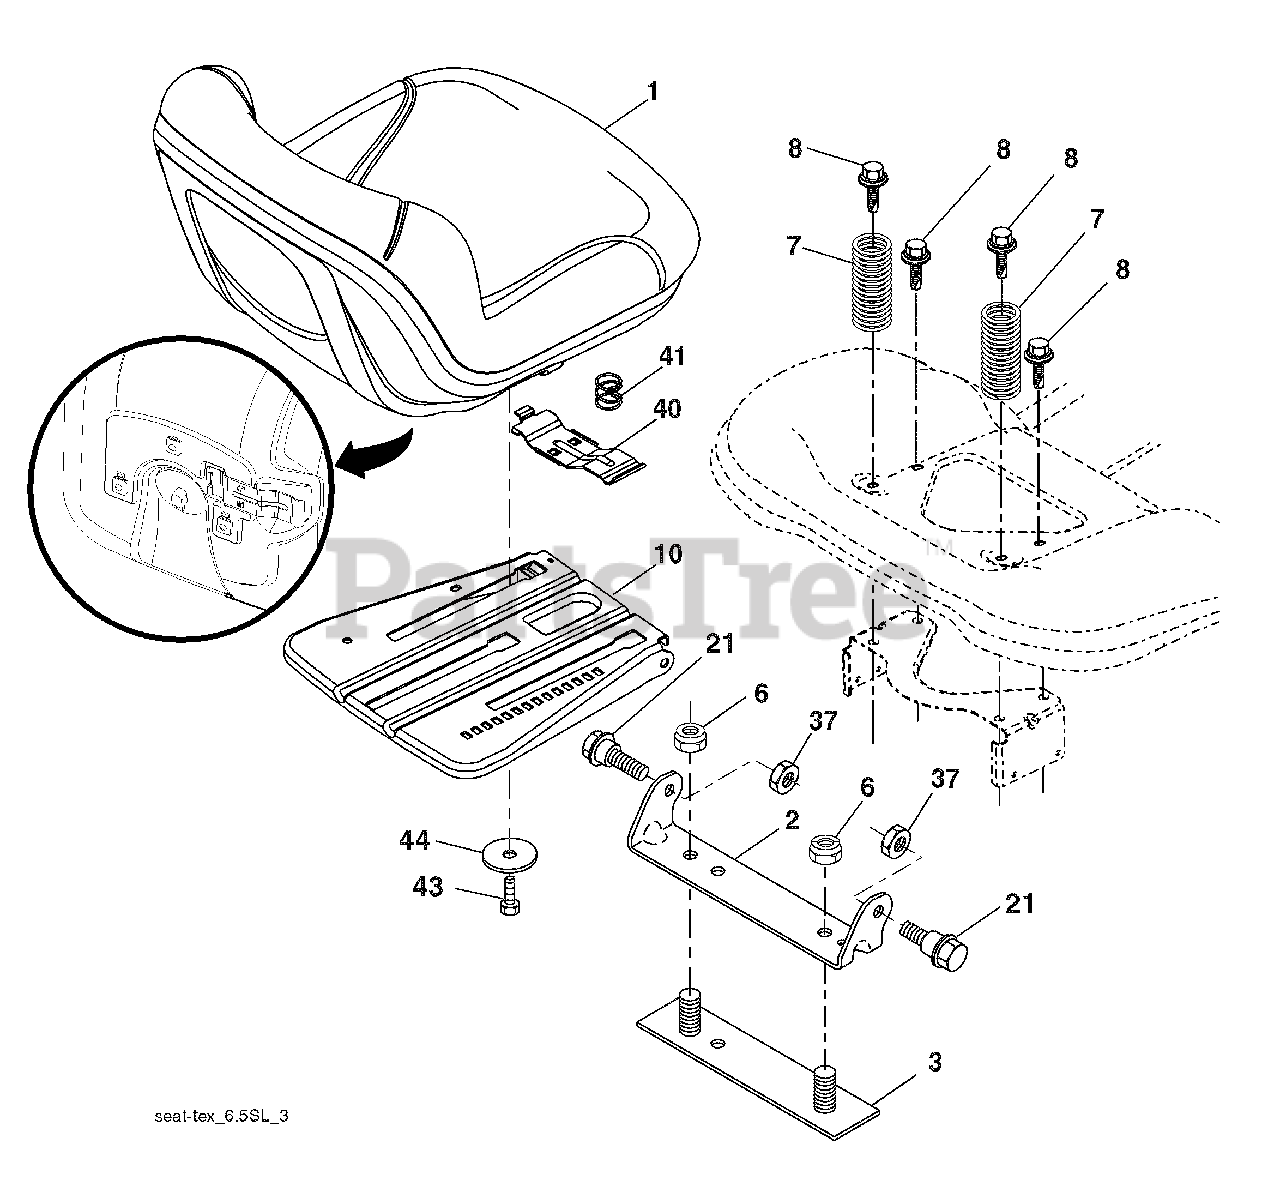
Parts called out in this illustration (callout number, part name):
1	Seat
2	Bracket Pivot Fender
3	Strap, Asm Fender
6	Nut, Lock w/Ins. 3/8-16 unc
7	Spring, Seat Cprsn
8	Bolt 5/16-18 unc x 3/4 w/Sems
10	Pan, Seat
21	Bolt, Shoulder 5/16-18
37	Nut, Lock 5/16-18 unc
40	Handle Slide Seat
41	Spring Latch Seat
43	Bolt Fin Hex 3/8-16 unc x 3/4
44	Washer 13/32 x 2-3/8 x 12 Ga.
